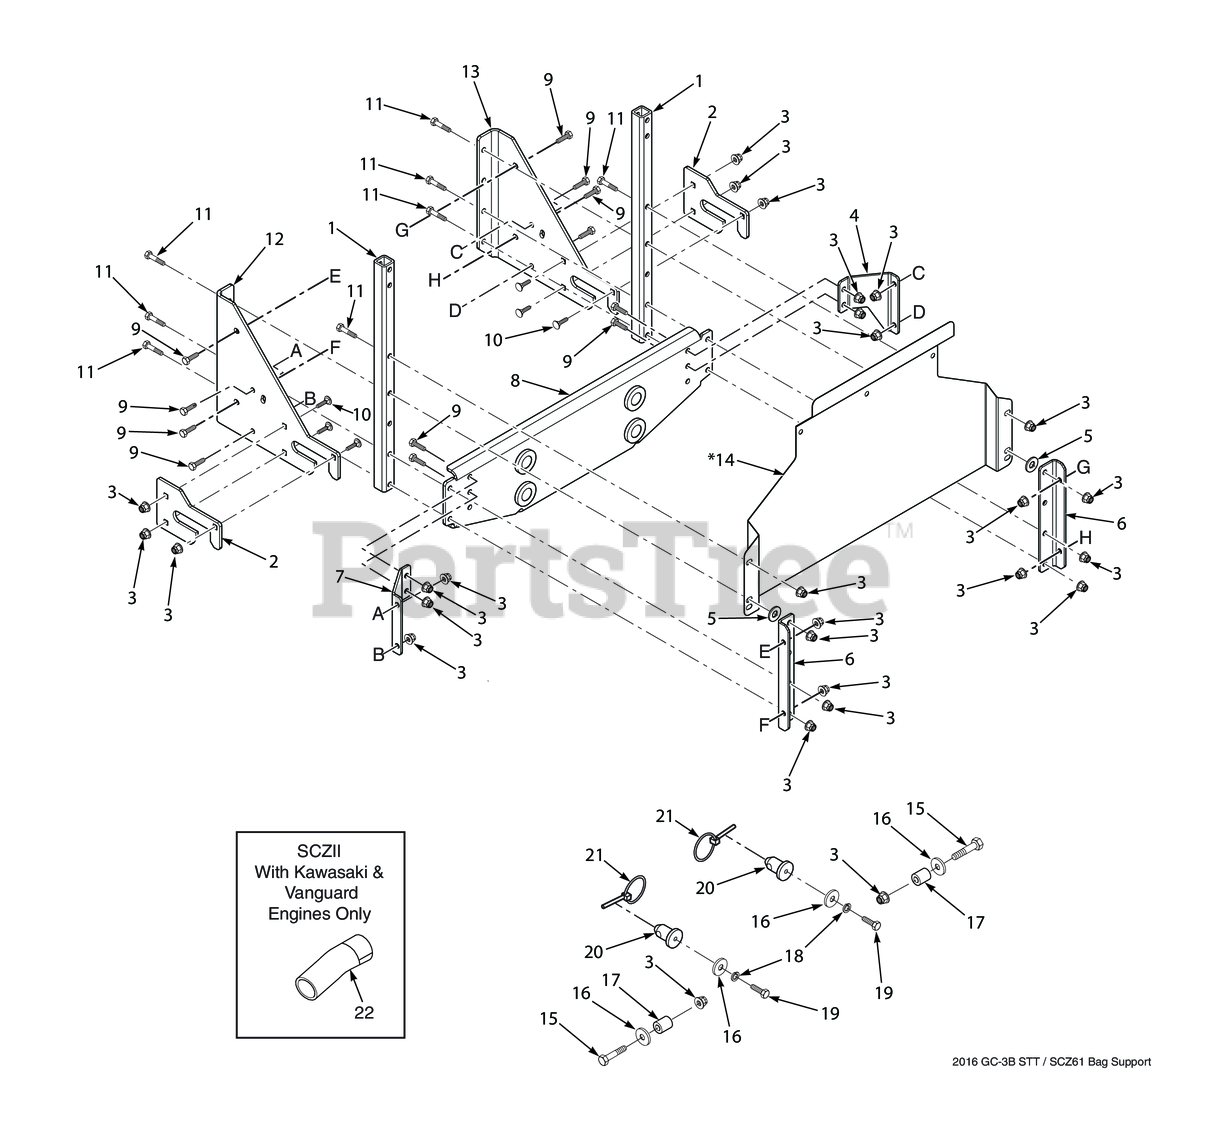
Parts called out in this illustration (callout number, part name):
1	Tube, Upright
2	Wear Plate, GC
3	Nut, Flange Elastic Stop Nut, 3/8-16
4	Angle Brace, LH GC
5	Flatwasher, 7/16-.469 x 1.75 x .25 (48, 52)
6	Mounting Bracket, GC Tube
7	Angle Brace, RH GC
8	Mounting Bracket Weldment
9	Bolt, Hex Head 3/8-16 x 1"
10	Carriage Bolt, 3/8-16 x 1.0"
11	Capscrew, Hex Head 3/8-16 x 2-1/2"
12	RH Mounting Bracket, GC
13	LH Mounting Bracket, GC
15	Bolt, Hex Head 3/8-16 x 2-1/4" - 61"
16	Flatwasher, 3/8-.406 x 1-1-1/2 x 7 Gauge
17	Spacer
18	Lockwasher, 3/8" Spring, Kawasaki FX / FS
19	Bolt, Hex Head 3/8-16 x 1-1/4" Grade 8
20	Pin, GC Locator
21	Quick Pin, 5/16" Dia.
22	Pipe, Muffler Extension - FX921
22	Pipe, Muffler Extension - 37 BV-EFI
